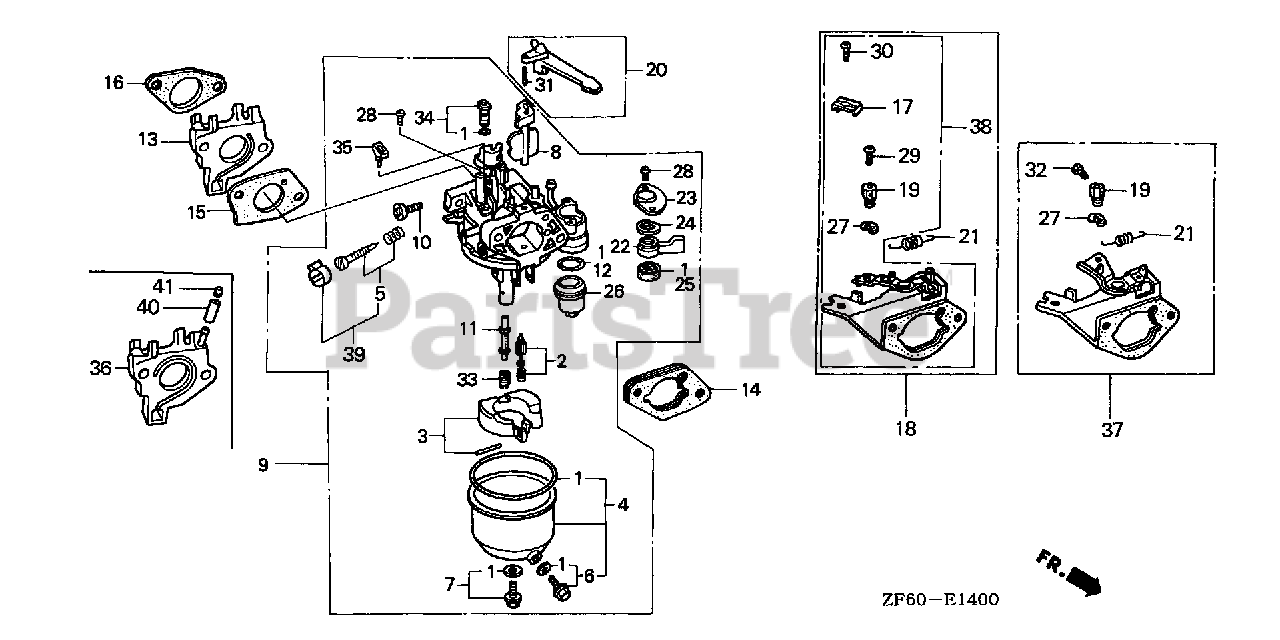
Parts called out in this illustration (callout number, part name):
1	GASKET SET (CARBURETOR NO.) (INCLUDES 16173-001-004)
2	VALVE SET, FLOAT (CARBURETOR NO.)
3	FLOAT SET (CARBURETOR NO.)
4	CHAMBER SET, FLOAT (CARBURETOR NO.)
6	SCREW SET, DRAIN (CARBURETOR NO.)
7	SCREW SET (CARBURETOR NO.)
8	CHOKE SET (CARBURETOR NO.)
9	CARBURETOR ASSY. (BE85B B)
10	SCREW, THROTTLE STOP (CARBURETOR NO.)
11	NOZZLE, MAIN (CARBURETOR NO.)
12	GASKET, FUEL STRAINER CUP (CARBURETOR NO.)
13	INSULATOR, CARBURETOR
14	SPACER, CARBURETOR
15	GASKET, CARBURETOR
16	GASKET, INSULATOR
20	LEVER, CHOKE (STD)
22	LEVER, PETCOCK (CARBURETOR NO.)
23	PLATE, LEVER SETTING (CARBURETOR NO.)
24	SPRING, PETCOCK LEVER (CARBURETOR NO.)
25	GASKET, PETCOCK (CARBURETOR NO.)
26	CUP, FUEL STRAINER (CARBURETOR NO.)
28	SCREW, PAN (3X6)
28	SCREW, PAN (3X8) (CARBURETOR NO.)
31	PIN, SPRING (2X12)
33	JET, MAIN (#88) (CARBURETOR NO.)
33	JET, MAIN (#90) (CARBURETOR NO.)
33	JET, MAIN (#92) (CARBURETOR NO.)
34	JET SET, PILOT (#45) (CARBURETOR NO.)
35	COLLAR, SETTING (CARBURETOR NO.)
39	SCREW SET, PILOT (CARBURETOR NO.)
